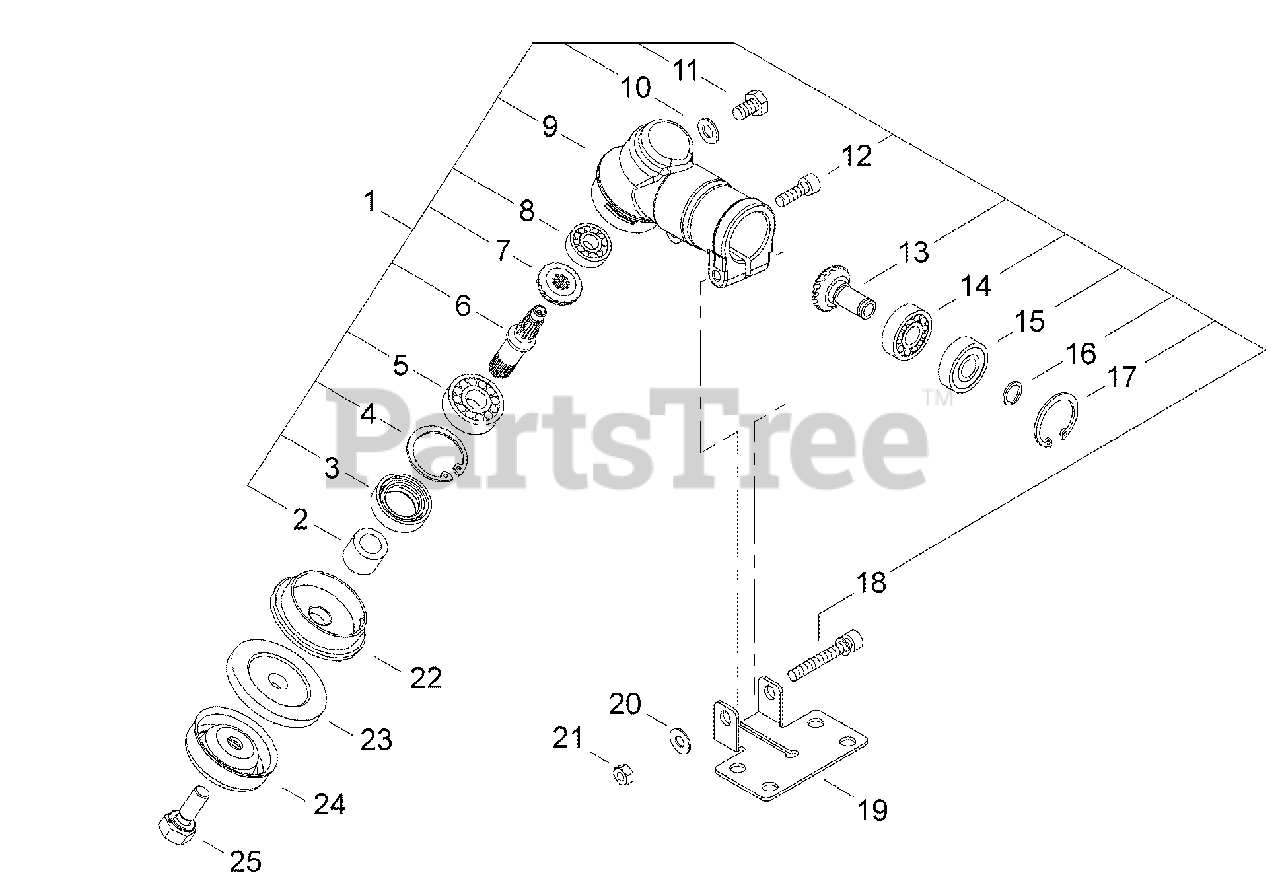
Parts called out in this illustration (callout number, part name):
1	GEAR CASE ASSY
2	COLLAR
3	SEAL, OIL
4	RING, RETAINING - 26
5	BEARING, BALL - 6000MOS
6	GEAR - SHAFT
7	GEAR - BEVEL
8	BEARING, BALL - 626MOS
9	CASE, GEAR
10	WASHER - 6
11	BOLT - 6X10
12	SCREW - 5X10
13	GEAR - SHAFT
14	BEARING, BALL - 609 MOS
15	BEARING, BALL - 609Z MOS
16	RING, RETAINING - 9
17	RING, RETAINING - 24
18	SCREW - 5X40
19	MOUNTING PLATE, SHIELD
20	WASHER - 5
22	HOLDER - A
23	CLIP
24	GUARD
25	SCREW - 7X20
